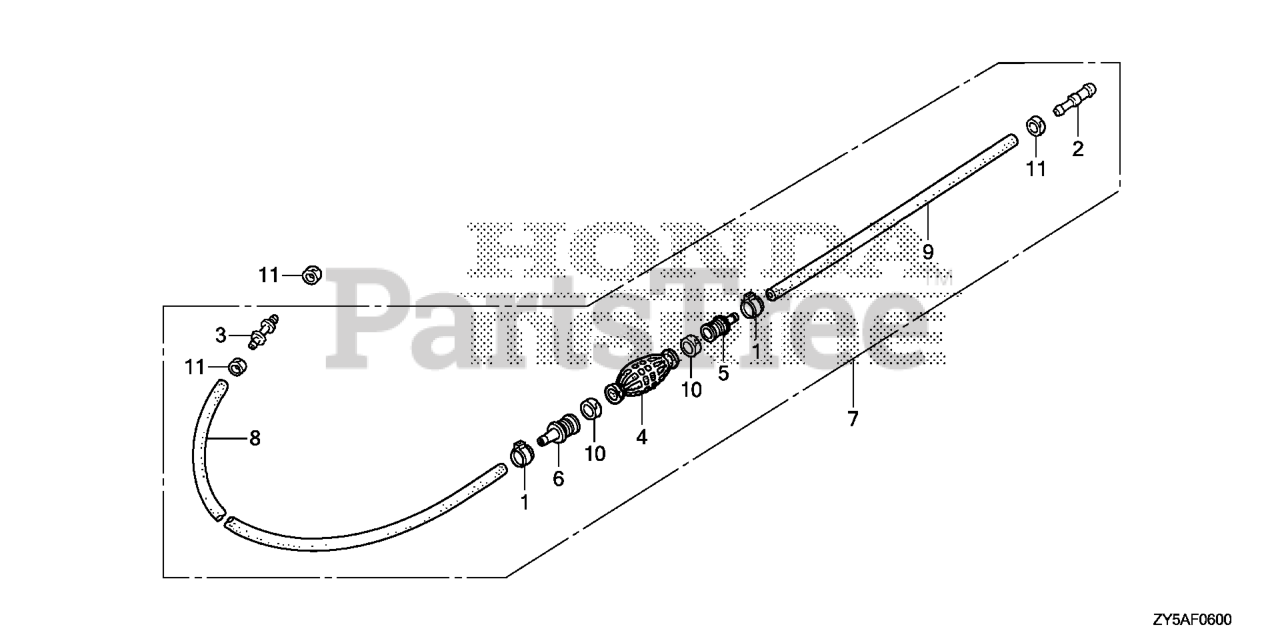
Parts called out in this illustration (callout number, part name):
1	CLAMP, FUEL TUBE (14.0) (CONNECTOR TYPE)
2	JOINT, FUEL TUBE (JOINT TYPE)
3	JOINT, FUEL TUBE
4	BULB, PRIMER
5	VALVE, IN.
6	VALVE, OUTLET
7	TUBE, FUEL TANK
8	TUBE, FUEL LONG (75)
8	TUBE, FUEL LONG (7.3X2000)
9	TUBE, FUEL SHORT
9	TUBE (75)
10	BAND, TUBE CLIP (20MM)
11	BAND, TUBE CLIP (12.5MM)
